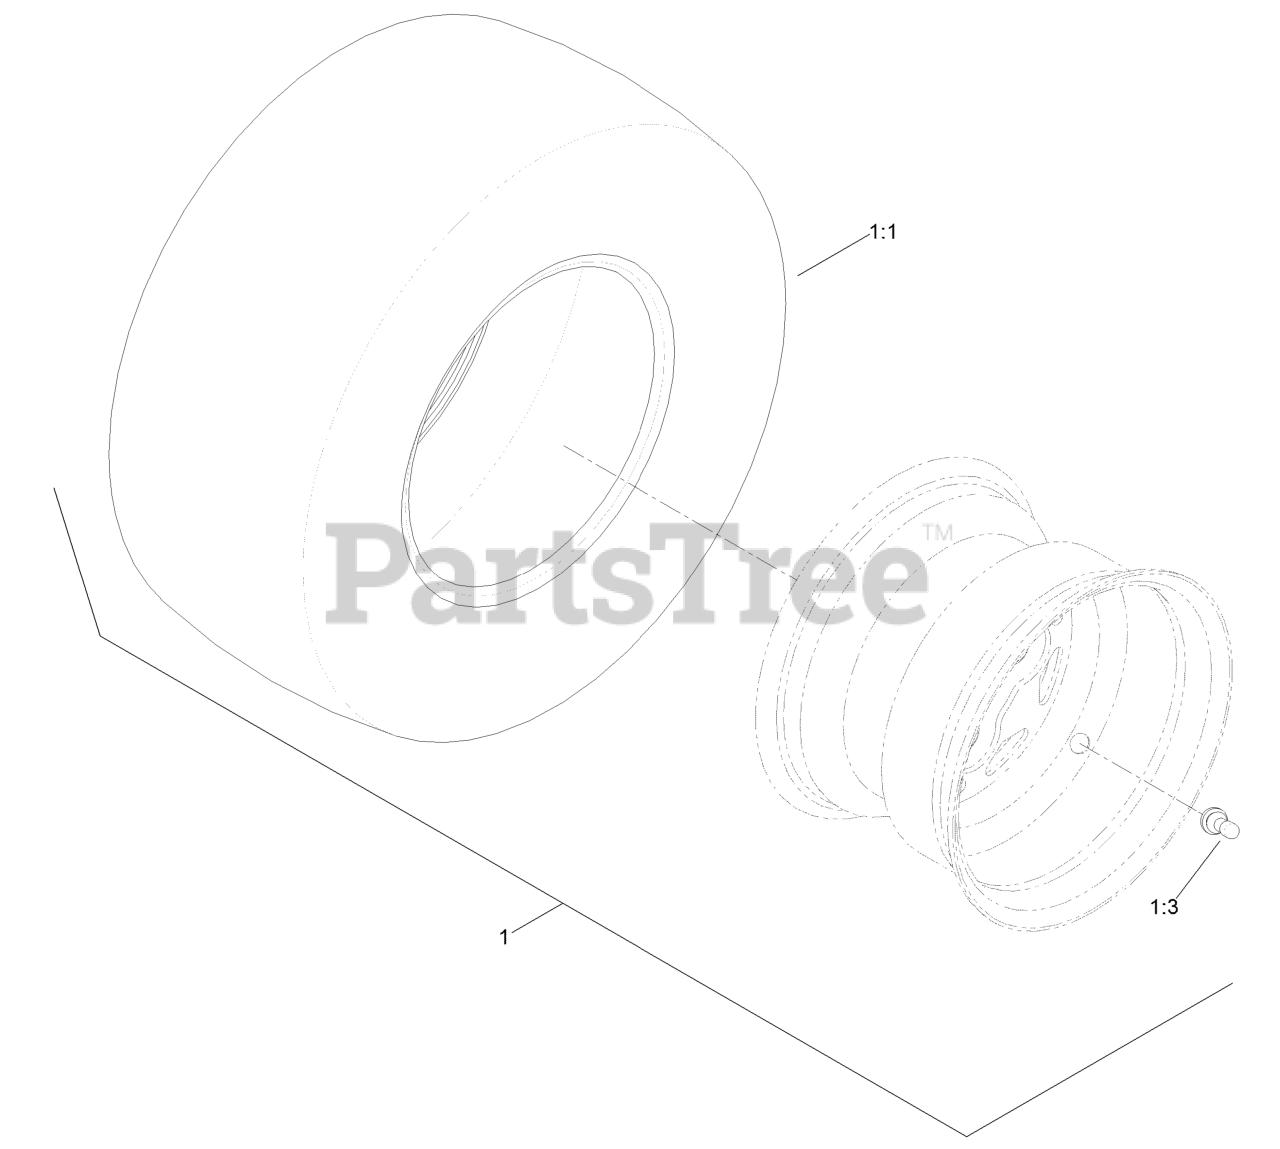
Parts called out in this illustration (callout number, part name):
1	Tire And Wheel ASM
1:3	Stem-Valve
1:99	Tube-Inner
